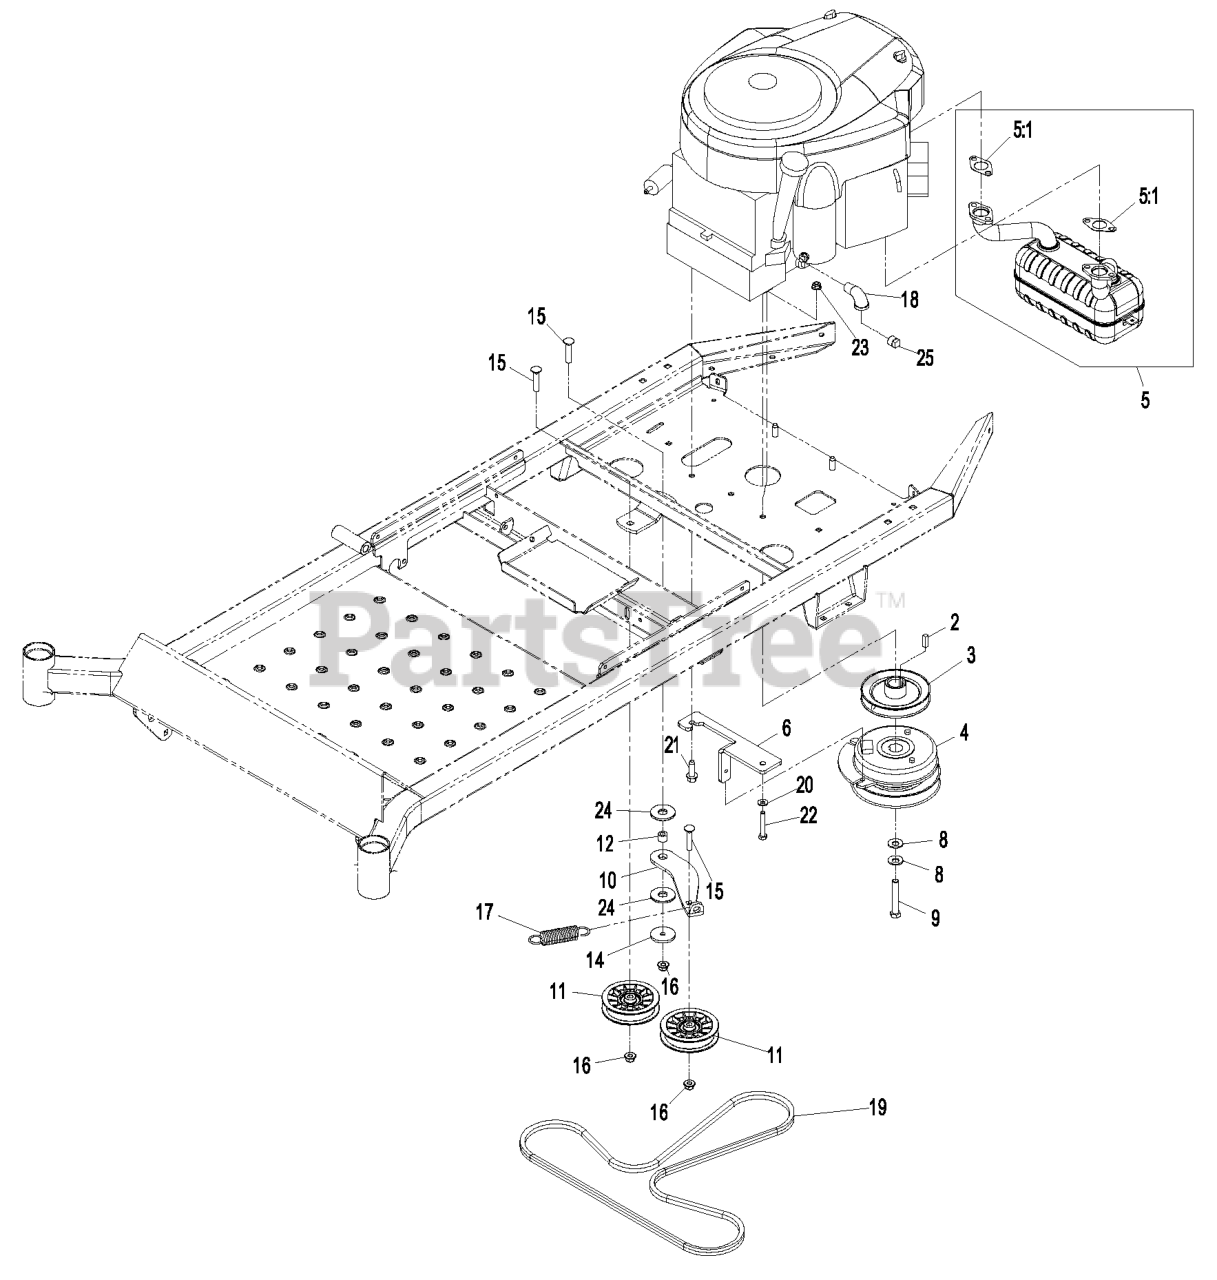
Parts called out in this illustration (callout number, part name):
3	SHEAVE-SPLIT STEEL
4	CLUTCH-ELECTRIC
5	MUFFLER ASM
5:1	GASKET-EXHAUST
6	ANCHOR-CLUTCH
8	WASHER-SPRING
9	SCREW-HH
10	ARM,DRIVE IDLER
11	PULLEY-IDLER, FLAT
12	BUSHING-LEVER, LIFT
14	WASHER-PLAIN
15	SCREW-CARR
16	NUT-HF, NI
17	SPRING-EXTENSION
18	ELBOW-90 DEG
19	V-BELT
20	WASHER-SPRING
21	SCREW-THD
22	SCREW-HH
23	NUT-HF, NI
24	WASHER-FRICTION, COMPOSIT
25	PLUG-PIPE, SQH
